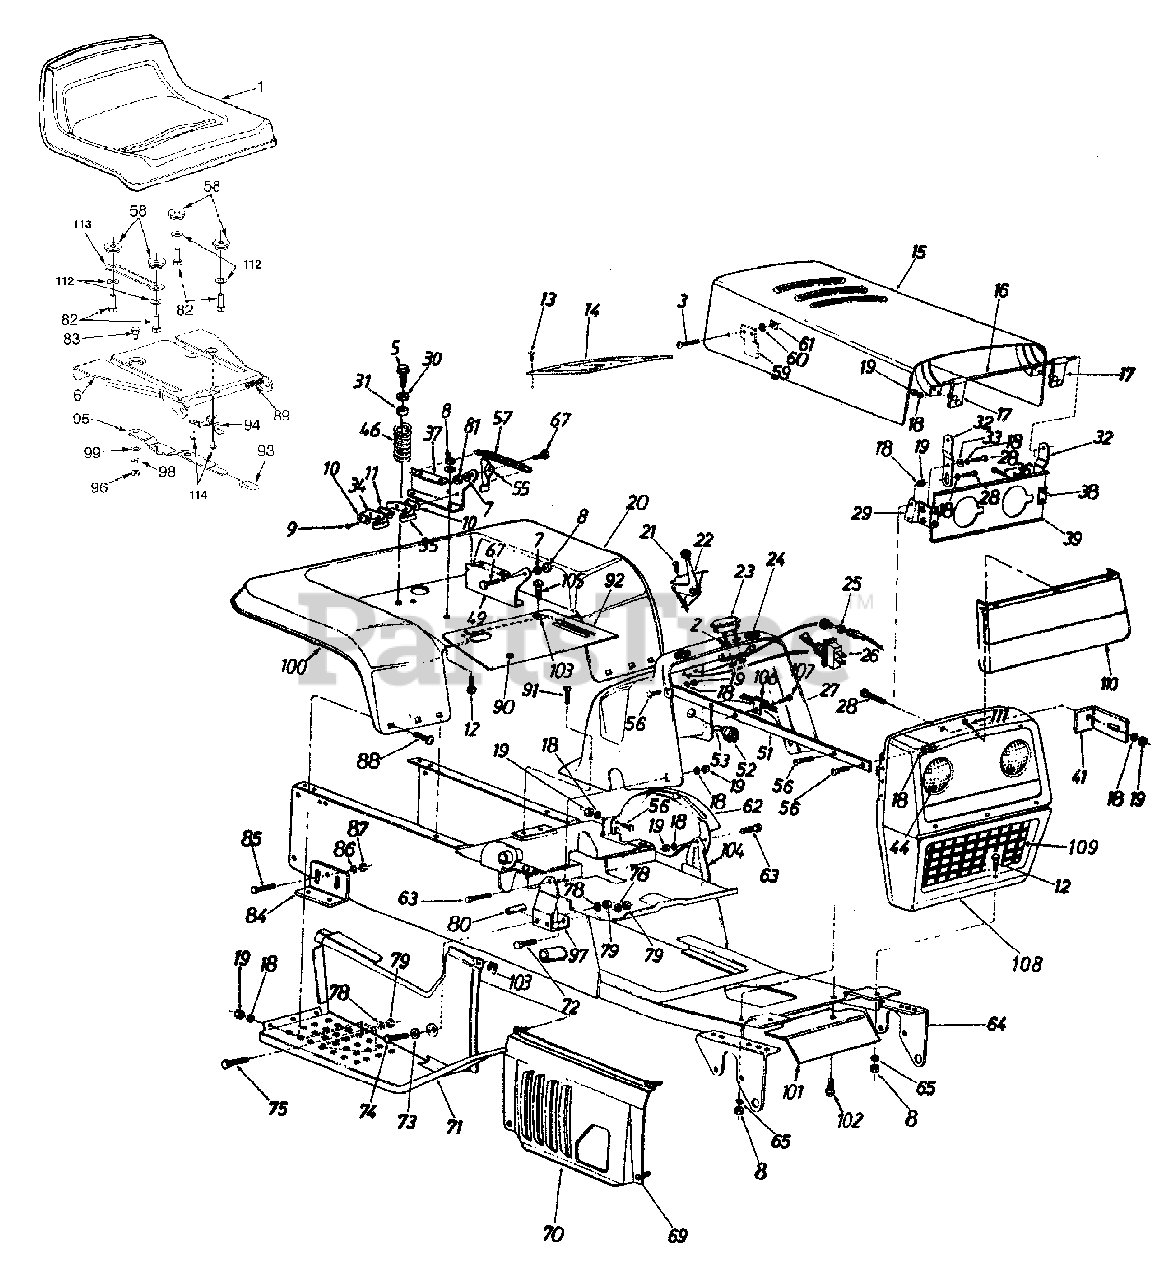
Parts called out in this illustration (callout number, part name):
1	Seat Assembly. (Yellow)
2	Lock Washer .190" I.D.
3	Truss Hd. Mach. Scr. #10-24 x .38"
8	Hex Nut 5/16-18 Thd. Grade 5
9	Hex Wash. Hd. AB-Tap Scr. #8 x .5"
10	Insulator Plate
11	Insulator Boss Plate
12	Hex Bolt 5/16-18 x .75" Lg.
13	Self-Tap Oval Hd. Scr. 1/2" Lg.
14	Dash Panel Cover
17	Hood Hinge Assembly.
18	L-Wash. 1/4" I.D.
19	Hex Nut 1/4-20 Thd.
22	Throttle Control
23	Ammeter
24	Rubber Bumper
25	Choke Control
26	Light Switch
27	Dash Panel
28	Hex Bolt 1/4-20 x .62" Lg.
29	Hood Support Brkt. Assembly.-R.H.
30	Fl-Wash. .344" I.D. x .875"
31	Bushing
34	Safety Switch (Seat)
35	Safety Switch (Seat)
36	Hex Bolt 1/4-20 x .38" Lg.
38	Hood Support Brkt. Assembly.-L.H.
41	Heat Shield Brkt.
44	Head Lamp
46	Compression Spring 4.5" Lg.
53	Ignition Key
55	Seat Lift Bracket
56	Hex Bolt 1/4-20 x .75" Lg.
57	Extension Spring 5.31" Lg.
58	Seat Spacer
59	Hood Spring
60	L-Wash. #10
61	Hex Nut #10-24 Thd.
67	Shld. Bolt .437" Dia. x .268"
69	Truss Mach. Scr. #10-24 x .5" Lg.
73	Fl-Wash. .385" I.D. x .62" O.D.
74	Hex Bolt 3/8-16 x 3.00" Lg.
75	Hex Bolt 3/8-16 x 1.00" Lg.Grade 5
78	L-Wash. 3/8" I.D.
79	Hex Nut 3/8-16 Thd.
80	Spacer .375" I.D. x .62" O.D. x 2"
81	Hex Nut 5/16-18 Thd. (Gr. 5)
82	Hex Bolt 3/8-16 x 1" Lg.
83	Shld. Bolt 1/4-20 Thd.
84	Transaxle Support Brkt.
85	Rd. Hd. Rib Neck Scr. 3/8-24
86	L-Wash. 3/8" I.D.
87	Hex Nut 3/8-24 Thd. (Gr. 5)
88	Carr. Bolt 1/4-20 x .50" Lg.
89	Compression Spring
90	Snap Bushing
91	Hex Wash. Hd. Tap Scr. 1/4-20 x .5"
94	Seat Stop
95	Seat Lever
96	Lock Nut 1/4-20 Thd.
99	Fl-Wash. .344" I.D. x .62" O.D.
100	Trim Strip 84" Lg.
103	Speed Nut #10-24 Thd.
104	Dash Panel Mtg. Brkt.-L.H.
105	Truss Mach. Scr. #10-24 x .5"
106	Clamp
107	Self-Tap Scr. 5/16 x .5" Lg.
110	Headlight Bezel
112	Fl- Wash. .406" I.D. x .875" O.D.
113	Seat Selector
114	Hex B-Tapp Scr. #10-16 x .38" Lg.
